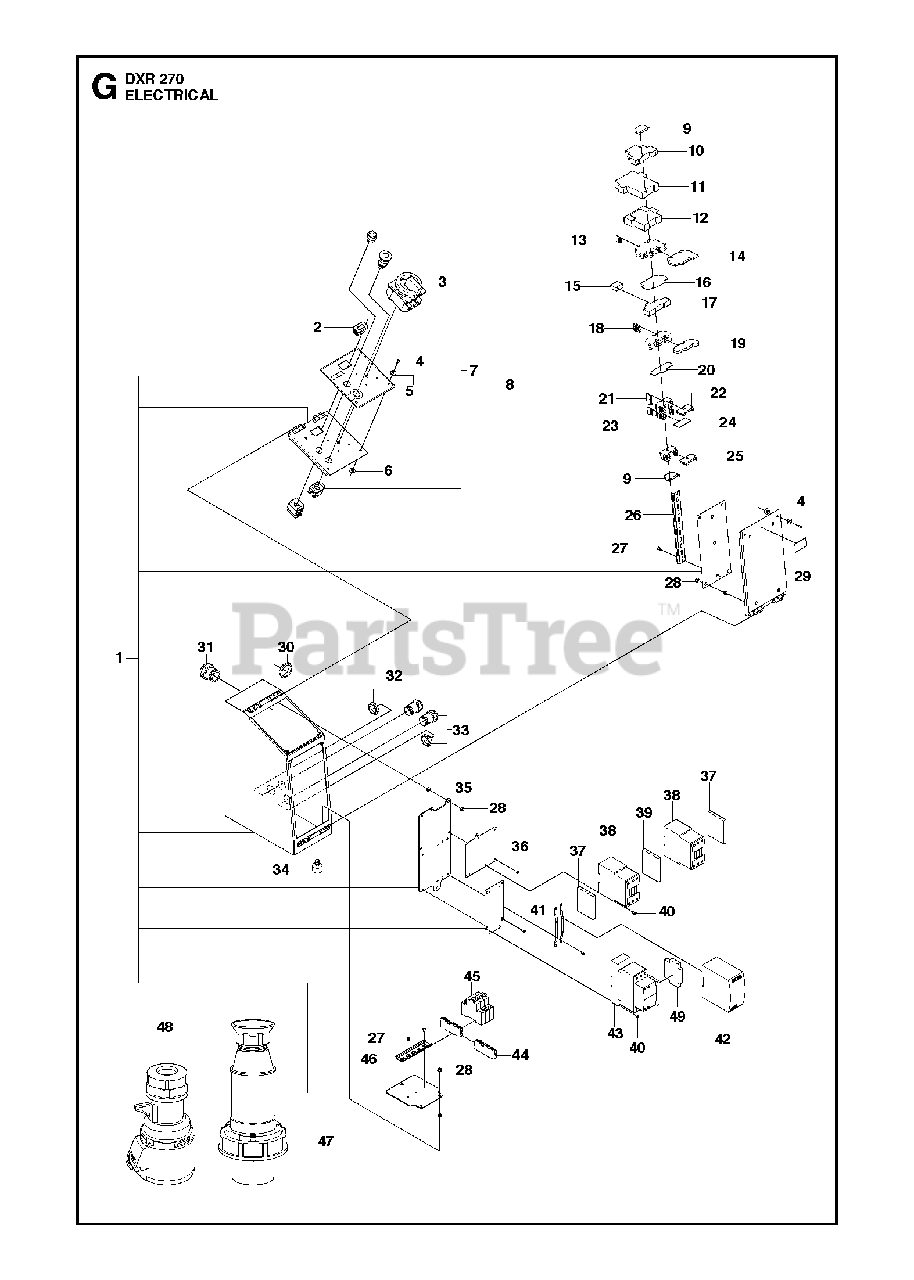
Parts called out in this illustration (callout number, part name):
10	CONTROLT3, Fan control relay
11	RELAYB1, Safety relay
12	RELAYK1, Phase sequence relay
35	HEXAGON THIN NUT
